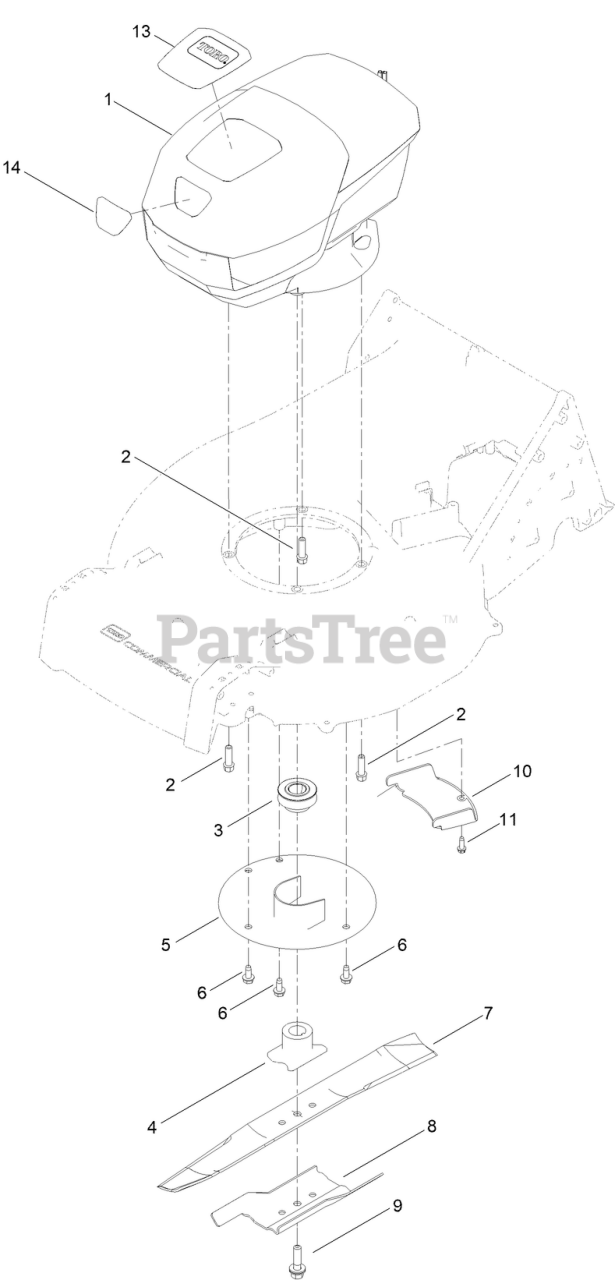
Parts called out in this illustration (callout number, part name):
1	MOTOR MODULE
2	SCREW-TAPTITE
3	PULLEY-DRIVER
4	DRIVER-BLADE
5	PROTECTOR-CRANKSHAFT
6	SCREW-HWHTF
7	BLADE-21IN, RECYCLING
8	ACCELERATOR-BLADE
9	BOLT-BLADE
10	COVER-BELT
11	SCREW-HWHTF
13	DECAL-HOOD, TOP
14	DECAL-HOOD, FRONT
